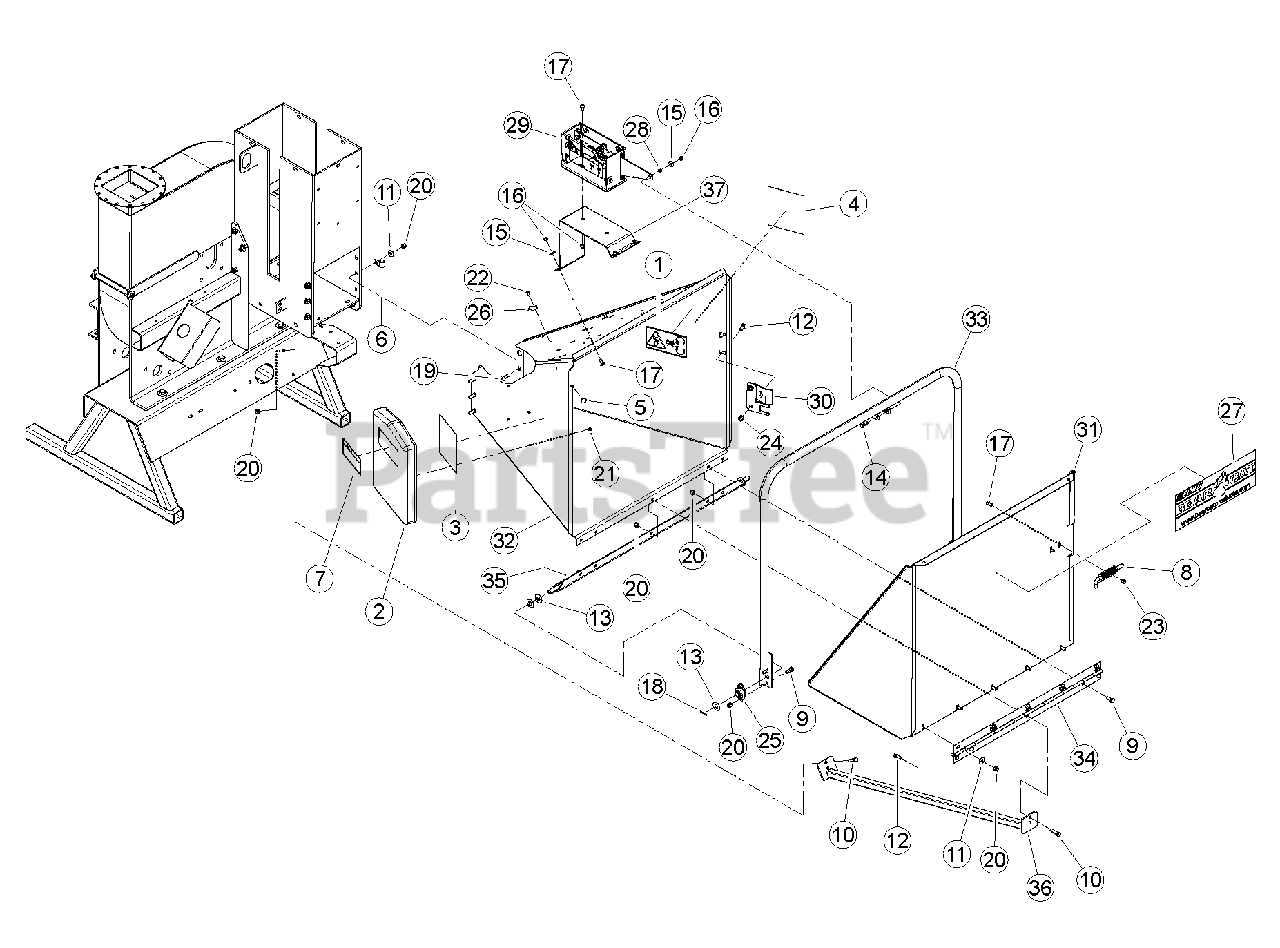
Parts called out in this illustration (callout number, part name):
1	DECAL, BLADE DANGER ISO
2	CONTAINER, INSTRUCTION MANUAL
3	DECAL, FEED POSITION
4	DECAL, FEED POSITION
5	BUMPER, RUBBER
6	CLAMP, 9/16 COATED
7	DECAL, MUTILINGUAL MANUAL
8	LATCH, RH HINGE
9	BOLT, 3/8 X 1 HEX GR5 ZP
10	BOLT, 3/8 X 1-1/2 HEX GR5 ZP
11	WASHER, 3/8 FLAT ZP
12	BOLT, 3/8 X 1 CRG GR5 NC ZP
13	WASHER, 5/8 SAE FLAT ZP
14	BOLT, 5/16 X 1 HEX GR5 NC ZP
15	WASHER, 5/16 FLAT ZP
16	NUT, 5/16 NE NYLOCK ZP
17	BOLT, 5/16 X 3/4 CRG GR5 NC ZP
18	COTTER PIN, 1/8 X 1.00 ZP
19	BOLT, 3/8 X 1-1/4 CRG GR5 NC ZP
20	NUT, 3/8 NE NYLOCK ZP
21	RIVET, AL BLIND 1/4 X 1/2 DOME HEAD
22	RIVET, AL BLIND 1/4 X 3/4 DOME HEAD
23	NUT, 5/16-18 NYLOCK-FLANGE
24	NUT, 3/8-16 NYLOCK FLANGE
25	BEARING, SIDE FLANGE MOUNT 5/8
26	CLAMP, CABLE MOUNT
27	DECAL, BEARCAT WEB
28	SPACER, IDLER PIVOT
29	ASSEMBLY, SWITCH BOX
30	PLATE, TRAY STOP
31	WELDMENT, CHUTE EXTENSION TRAY
32	WELDMENT, BIG CHIPPER CHUTE
33	WELDMENT, CONTROL ARM
34	HINGE, EXTENSION TRAY
35	WELDMENT, CONTROL PIVOT
36	WELDMENT, CHUTE SUPPORT
37	MOUNT, SWITCH BOX
